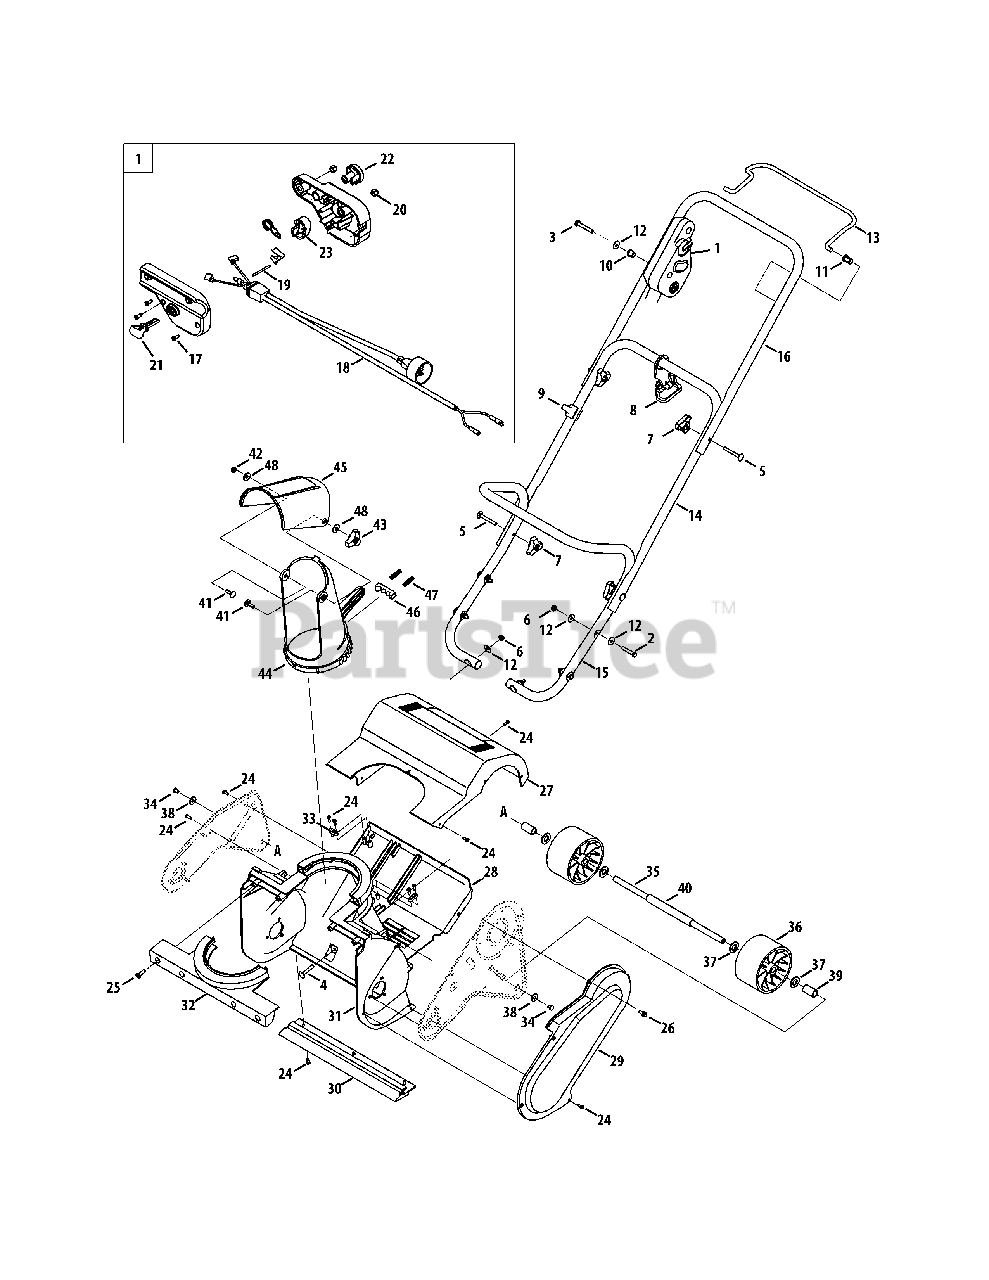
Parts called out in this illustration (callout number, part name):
1	Switch, Assembly
2	Screw, M6-1, 35.00
3	Hex Screw, 1/4-20, 2.0, Gr5, Std
4	Screw, Carriage, M6-1,35, Cl 8.8
5	Screw, Carriage, M6-1,45, Cl 8.8
6	Nut, Hex Lock, M6-1, Nylon
8	Retainer, Cord
9	Cable, Guide
10	Sleeve, Insl, 7.40mm x 13mm
11	Sleeve, Insl, 8mm x 11mm OD
12	Washer, Flat, 6.4 Id x 18 OD
13	Bail, Electric Switch
15	Handle, Lower, Lift Type
16	Handle, Upper
17	Screw, 10-9x.50
18	Harness Assembly, 120v
19	Shaft, Pivot, Switch
20	Nut, Hex Lock, 1/4-20, Gr8, Nylon
22	Clip, Bail Lock
23	Button, Bail Lock
24	Screw, Tap, M4.2 x 1.4 x 13
25	Screw, Tap, M6.3 x 1.8 x 20
26	Screw, Mach, M5 x 0.8 x 13
27	Cover, Top
28	Cover, Engine, Lower
29	Cover, Belt
30	Blade, Scraper
31	Housing, Auger, Red
32	Cover, Front, Red
33	Bracket, Cord, Holder
34	Screw, Hex Screw, M6 x 8mm
35	Shaft, Roller, Wheel
36	Wheel, Roller
37	Washer, Flat, M12
38	Washer, Flat, 6.4 Id x 18 OD
39	Spacer, 13.0 x 17.0 x 30.0
40	Spacer, 13.0 x 17.0 x 134.0
41	Screw, Carriage, M6-1, 20.00
42	Nut, Hex Lock, M6-1
44	Chute, Lower, Snow
45	Chute, Upper
46	Bracket, Chute, Ratchet
47	Spring, Compression x 1.0, .8
48	Washer, Bell, .265 x .750 x .062
